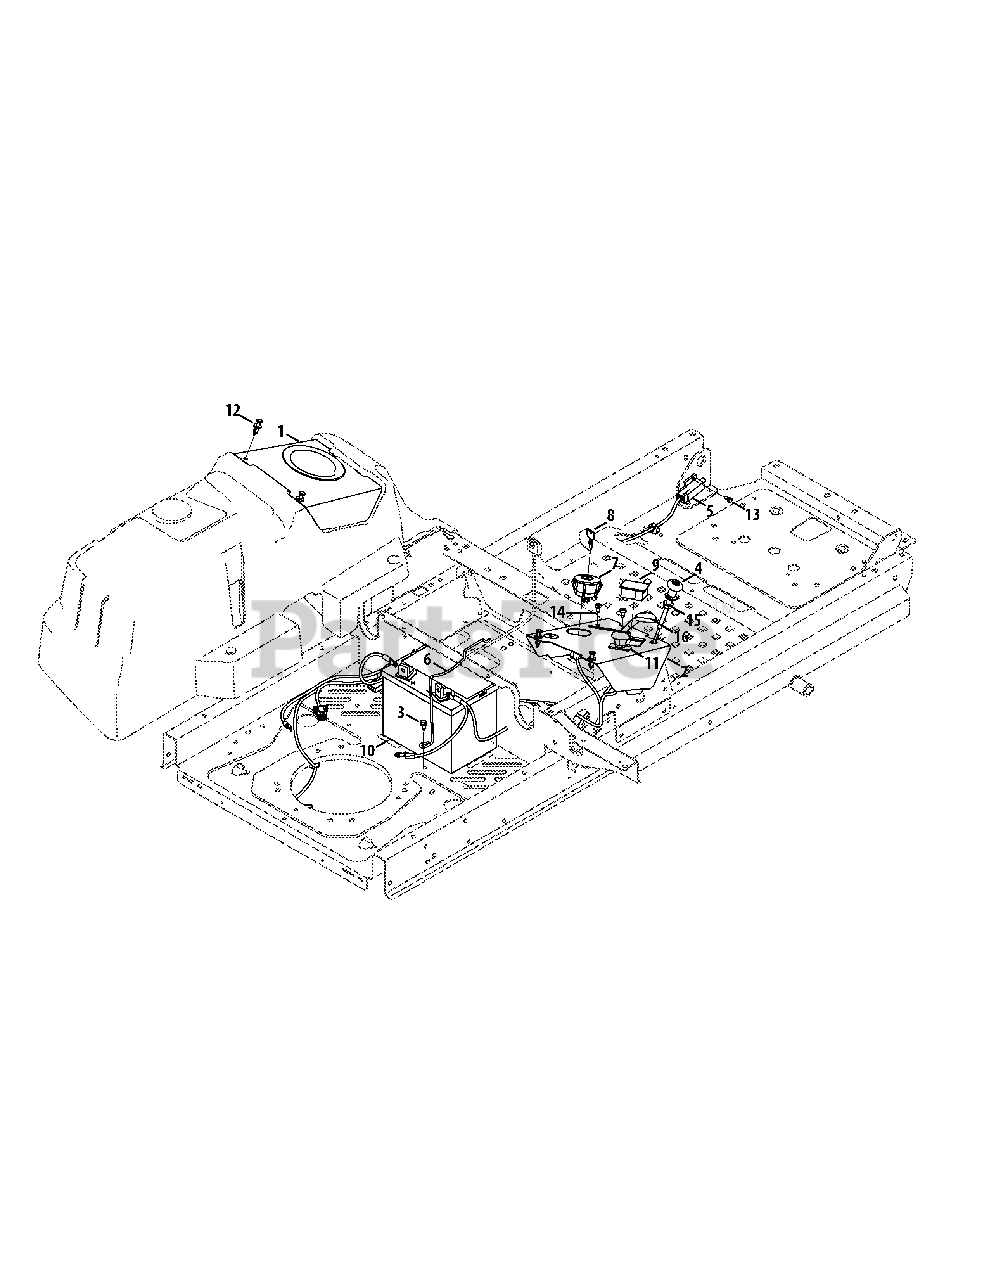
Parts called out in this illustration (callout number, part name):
1	Console Cover, LH
2	Console Cover, RH
3	Hex Washer Screw, 1/4-20 x .625
4	Choke Cable
5	Interlock Switch
7	Key Switch
8	Key, Assembly
9	Hour Meter/Service Minder
11	Electric PTO Switch
12	Plastic Rivet
13	Shoulder Screw, #10-32 x .500
14	Screw, 1/4-20 x .50
15	Flange Lock Nut, 3/8-16
16	Throttle Cable, Command
